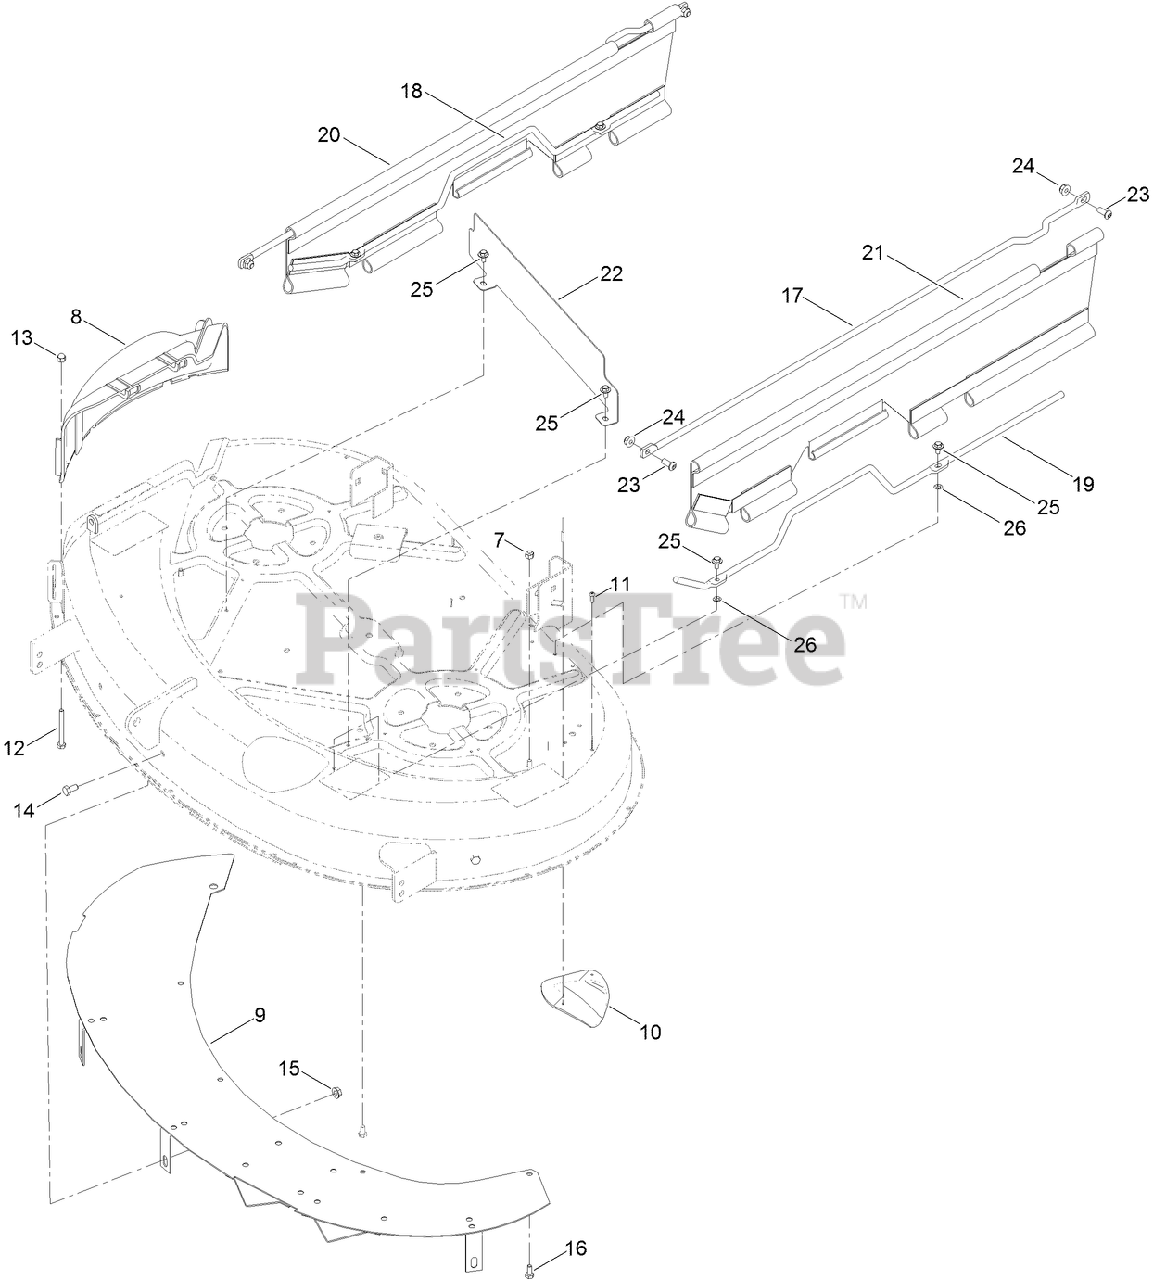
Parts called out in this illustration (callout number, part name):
7	NUT-LOCK, NI
8	COVER-DISCHARGE
9	BAFFLE UPPER ASM
10	PLATE-KICKER
11	SCREW-PPH
12	SCREW-HH
13	NUT-CAP
14	SCREW-HH
15	NUT-HF
16	SCREW-HH
17	ROD-SUPPORT, UPPER
18	ROD-SUPPORT, LOWER (RH)
19	ROD-SUPPORT, LOWER (LH)
20	RH GUARD SIDE
21	GUARD-SIDE, LH
22	SHIELD-FRONT, DECK
23	SCREW-HSBH
24	NUT-HF, NI
25	SCREW-HHFTF
26	NUT-RETAINING
